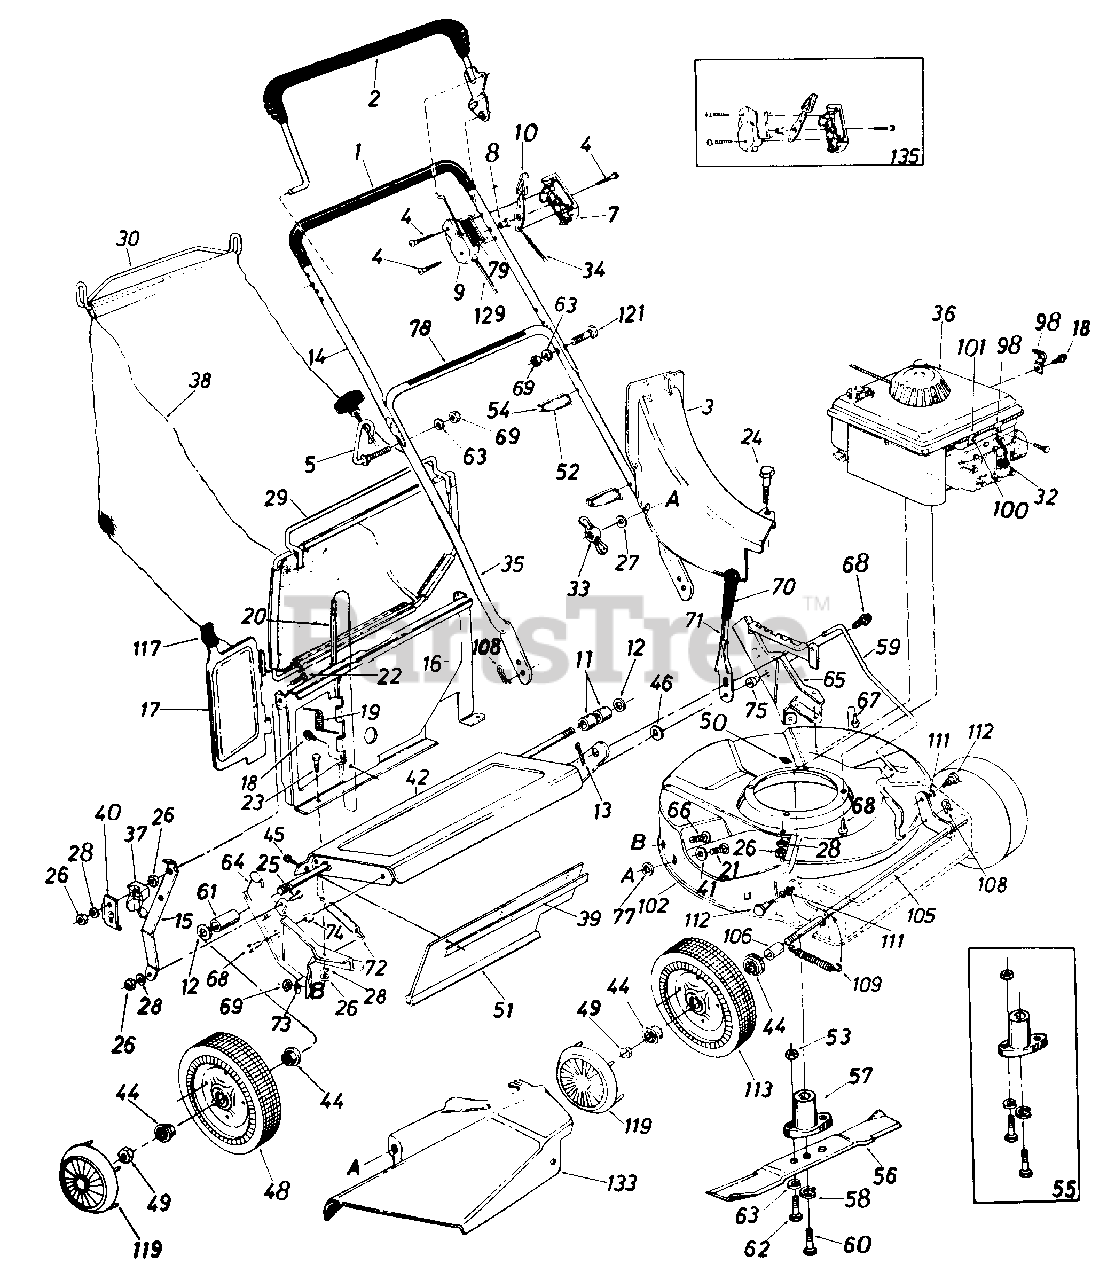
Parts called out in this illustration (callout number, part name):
1	GRIP-SHRINK-25 IN
2	HANDLE ASSY-CONTROL-LH
3	CHUTE ASSY-TOP DISCH
4	SCREW-TRUSS MACH
5	SCREW-RECOIL HANDLE GUIDE
7	PANEL HALF-CONTROL
8	PIN-CONTROL DISC
9	PANEL HALF-CLUTCH
10	LEVER-THROTTLE CONT-REV
12	WASHER-FL-.510 ID X .75 OD X .033
13	PIN-COTTER-3/32 DIA X .75
14	HANDLE-UPPER-CHROME
15	BRACKET-PANEL SUP
16	PANEL ASSY-CATCHER
17	DOOR-TOP DISCHARGE
18	SCREW-HEX B-TAP #10 X .38
19	SPRING-TORSION
21	BOLT-CARRIAGE 1/4-20 X .62
22	SCREW-TRUSS MACH 1/4-20 X 1.00
23	SCREW-HEX 1/4-20 X .50
24	SCREW-SHLD
25	SCREW-HEX 1/4-20 C .62
26	NUT-HEX 1/4-20
27	WASHER-FL
28	LOCK WASHER 1/4 DIA
29	FRAME-FRONT
30	HANDLE-GRASSCATCHER
32	INSULATOR-SPARK PLUG
33	NUT-INS WING L-1/4-20
34	WIRE-THROTTLE 58 LG
35	HANDLE-LOWER PAINTED
37	GUIDE-ROPE
38	BAG-GRASS-CONV
39	STRIP-RETAINING
40	CLIP-SPRING RETAINER
41	WASHER-FL-.344 ID X .62 OD X .033
42	AXLE-RR-PUSH ASSY
44	BEARING-BALL
45	SCREW-HEX WASH HD
46	WASHER-FL-.385 X 1.00 X .135
48	WHEEL ASSY W/TIRE
49	NUT-HEX INS L-1/2-20
52	TIE-CABLE
53	NUT-5/16-24
54	TIE-CABLE
55	KIT-BLADE ADAPTER
56	BLADE-21IN
57	ADAPTER-BLADE
58	WASHER-HDL 3/8
59	ROD-HGT ADJ
60	SCREW-HEX 3/8-24 X 2.25
61	SPACER-.513 ID X .703 OD X .69
62	SCREW-HEX SPECIAL 5/16-24X1.0
63	WASHER-LOCK-5/16
64	BRACKET ASSY-HDLE-RH
65	BRACKET ASSY-HDLE-LH
66	BOLT-CARRIAGE 5/16-18 X .62
67	SCREW-HEX WASH HD 5/16-18X1/2
68	SCREW-HEX
69	NUT-HEX 5/16-18
71	LEVER-HGT ADJ
72	SPRING-EXTENSION
73	WASHER-BELL .337 X .867 X .057
75	SPACER-SHLD .500 X .100
77	RETAINER-BOLT 1/4X.50 OD
98	CLAMP-CASING
100	SCREW-HEX WASH HD TAP
101	CLAMP-CASING
102	DECK ASSEMBLY-20IN-TOP
105	AXLE ASSY-FR-290
108	PIN-INTERN COT-5/16 DIA
109	SPRING-EXTENSION
111	WASHER-INTERN L 3/8 X.56 OD X .018
112	SCREW-SHLD .623 X .425
113	WHEEL ASSY W/TIRE
119	HUB CAP-BLACK
121	BOLT-CARRIAGE-CURV 5/16-18 X 1.38
129	CABLE-CONTROL
133	DEFLECTOR ASSY
135	KIT-THROTTLE CONTROL
